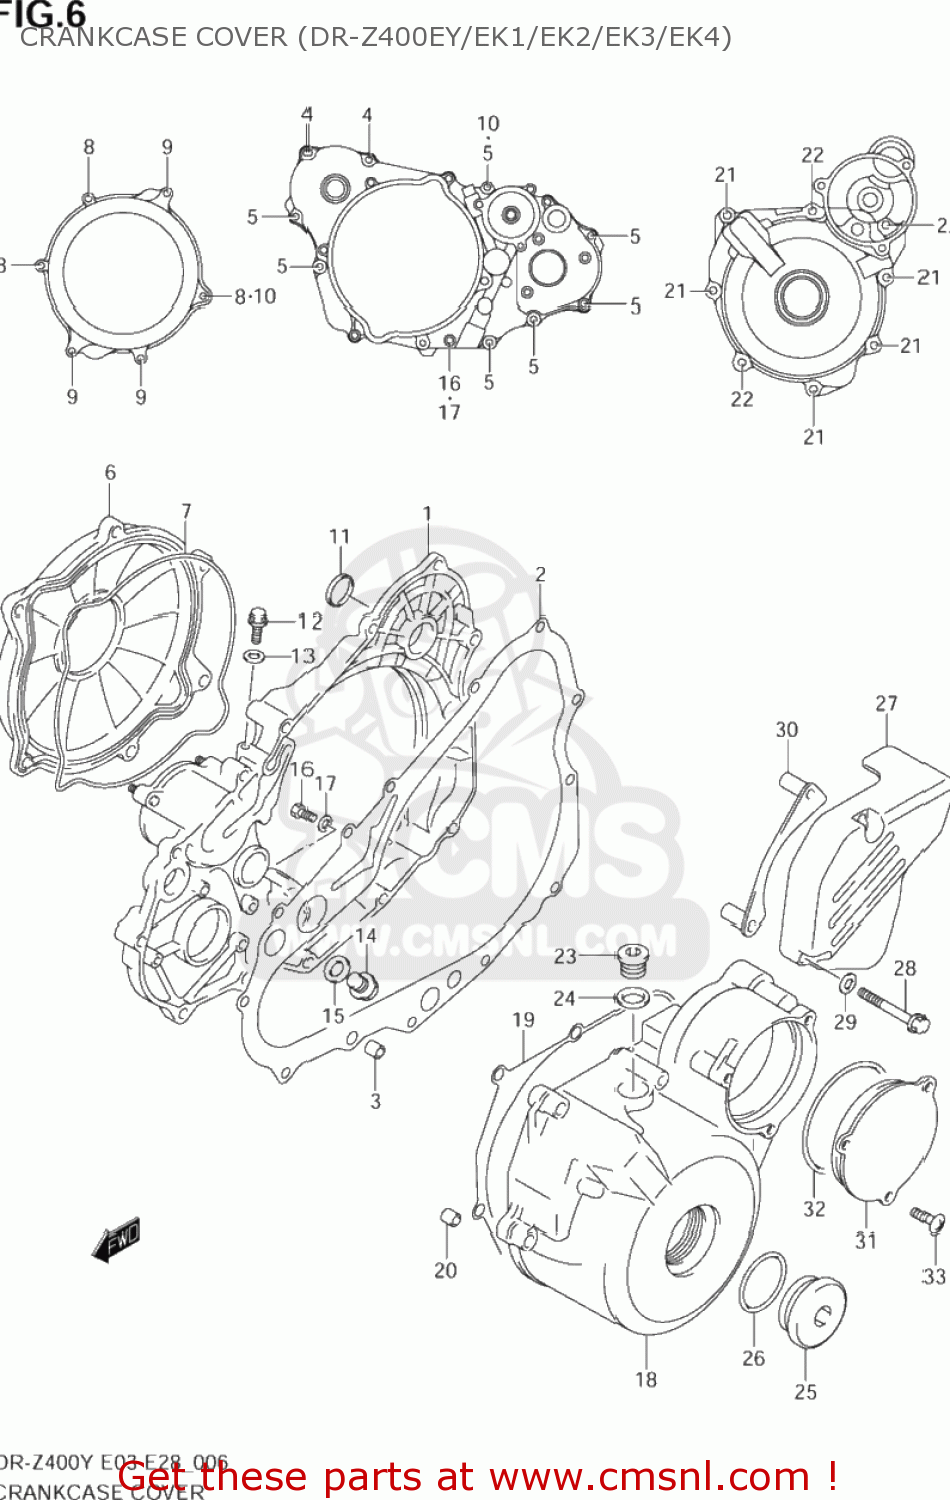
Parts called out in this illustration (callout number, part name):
1	COVER,CLUTCH INNER
2	GASKET,CLUTCH COVER (NAS)
3	PIN
4	SCREW
5	BOLT,G/S SWITC
6	COVER,CLUTCH OUTER
7	O RING,CLUTCH COVER OUTER
8	SCREW
9	BOLT
10	GASKET(5.8X13X1.2) (NAS)
11	PLUG,CLUTCH COVER KICK
12	BOLT
13	GASKET(5.8X13X1.2) (NAS)
14	PLUG(12X10)
15	GASKET(12.1X16.2X3.7) (NAS)
16	BOLT
17	GASKET(6.2X11X1).2 (NAS)
18	COVER,MAGNETO
19	GASKET,MAGNETO COVER (NAS)
20	PIN
21	BOLT,G/S SWITC
22	BOLT
23	PLUG
24	GASKET(13.8X18.8X4.8) (NAS)
25	PLUG
26	O RING(D:3.1,ID:32.7)
27	COVER,ENGINE SPROCKET
28	BOLT
29	WASHER(6.5X14X2)
30	PLATE,FR CHAIN GUIDE
31	COVER,STARTER IDLE GEAR
32	O-RING
33	SCREW
